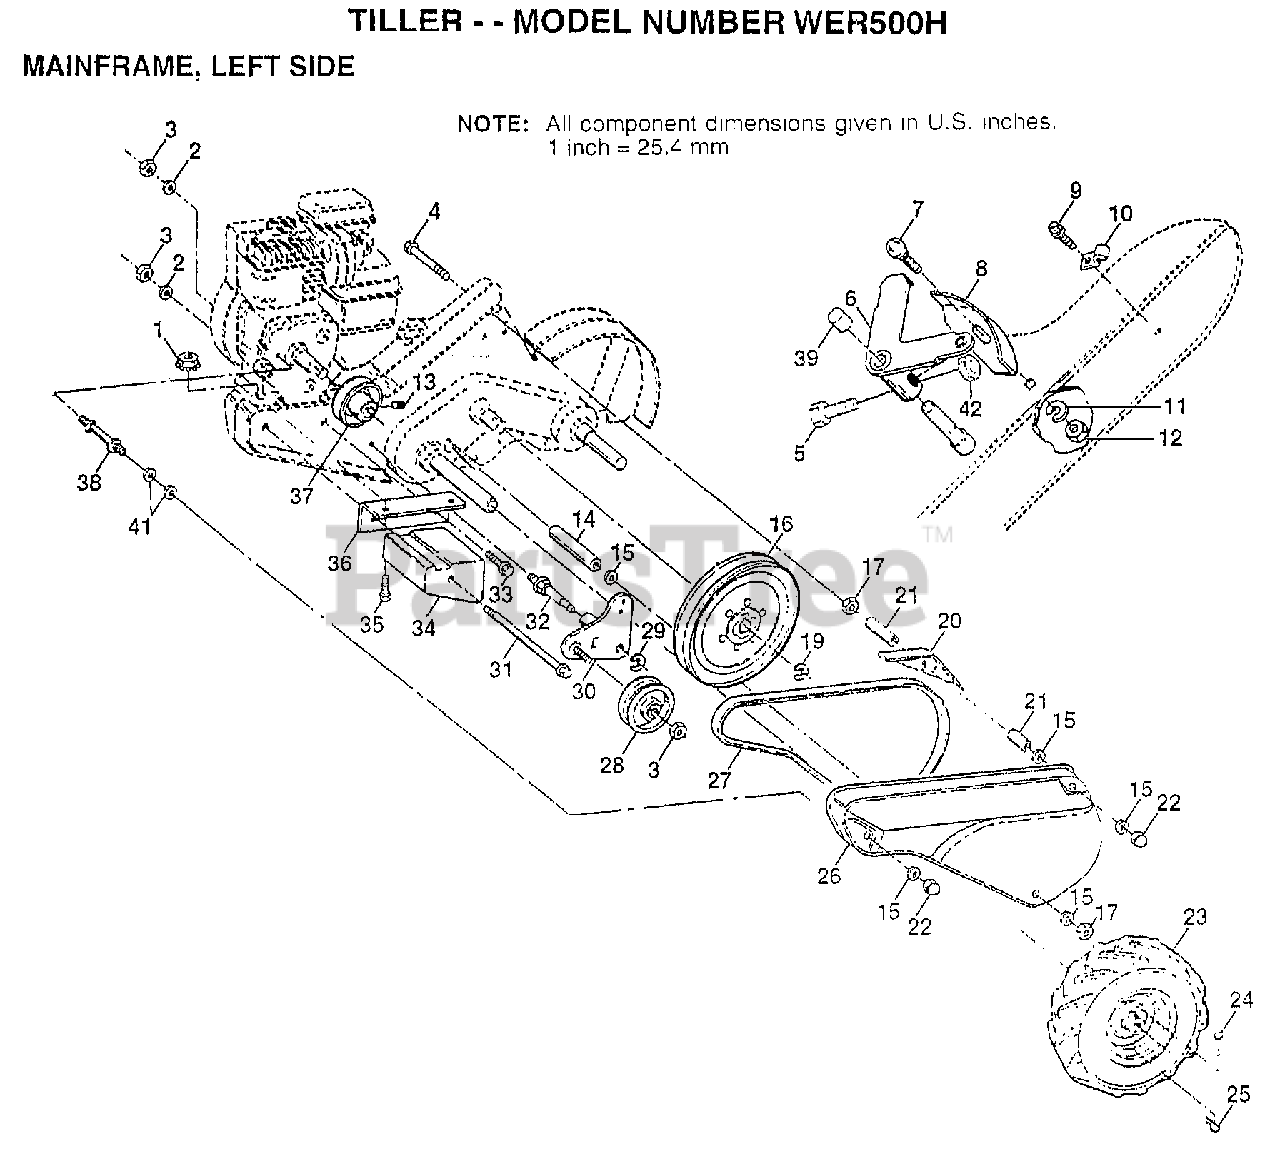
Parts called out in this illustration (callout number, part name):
2	LOCKWASHER
3	NUT.HEX.3/8-16UNC
4	BOLT TI
5	"SCREW-LEVER,SHI"
6	LEVER ASM CRT
7	BOLT
8	PANEL TI
10	CONDIUT CLIP T
11	LOCKWASHER
13	SET SCREW
14	SPACER
15	WASHER
16	SHEAVE.TRANS.
17	NUT.HEX.5/16-18
20	GUARD CRT
21	SPACER.SPLIT
22	NUT TI
23	TIRE.CHV.13X5.0-6
24	RIVET.DRILL.1.75
25	RETAINER M
26	GUARD.BELT.PNT.
27	BELT-V
28	PULLEY-IDLER TI
29	KLIP RING
30	BRACKET ASM IDLER
31	BOLT CRT
32	SHIFT ARM CRT
33	BOLT
34	COUNTERWEIGHT CRT
35	BOLT.HEX.5/16-1.5
36	BRACKET LH CRT
37	ENGINE SHEAVE
38	STUD.GUARD.BELT
39	CAP PLUNGER BLACK
41	WASHER
42	LOCKNUT
